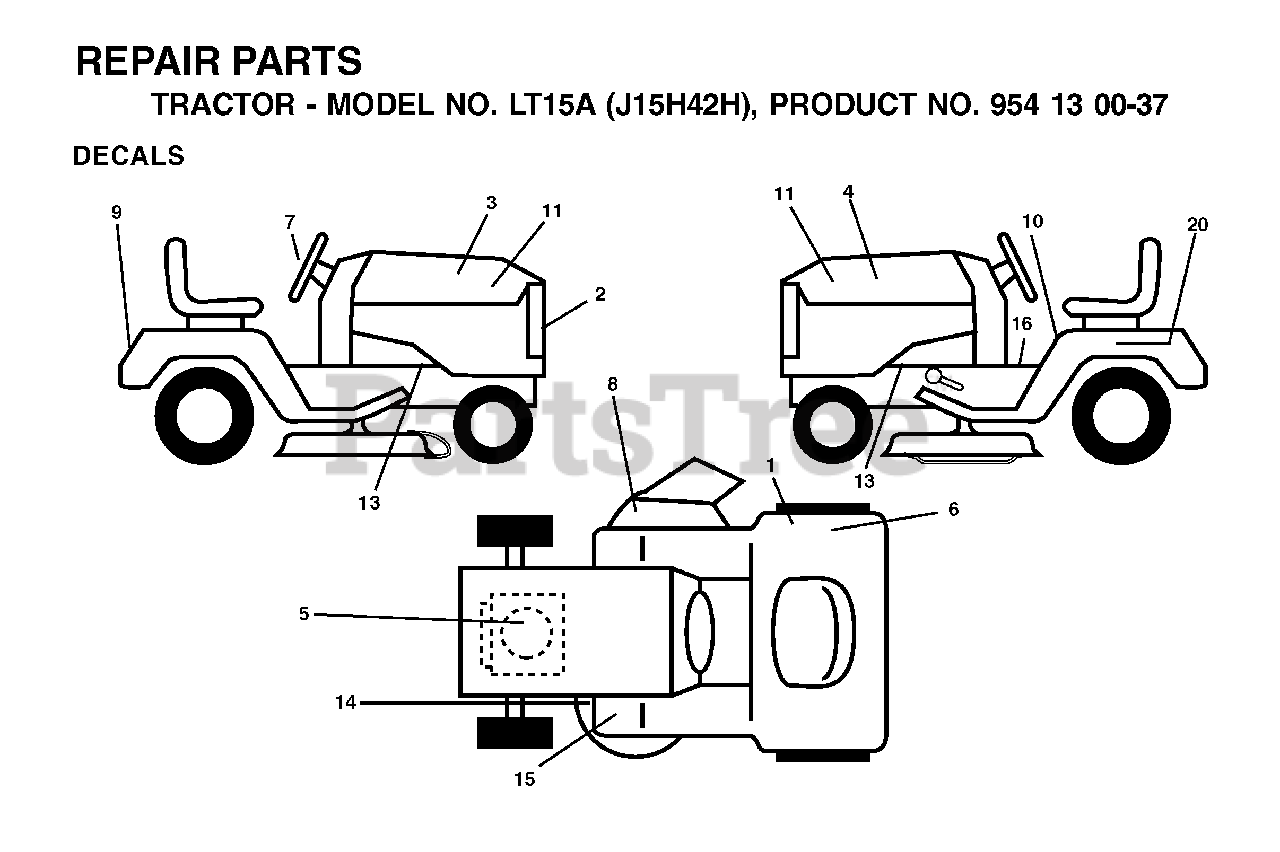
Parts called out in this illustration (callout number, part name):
1	DECAL CERTIFICATION
6	DECAL EUROPE STANDARD CE
8	DECAL MOWER CUT/FINGER
10	DECAL READ OWNER'S MAN SYMS
14	DECAL V BELT SCHEMATIC
16	DECAL PARK BRAKE
20	DECAL BTRY SYMBOLS
